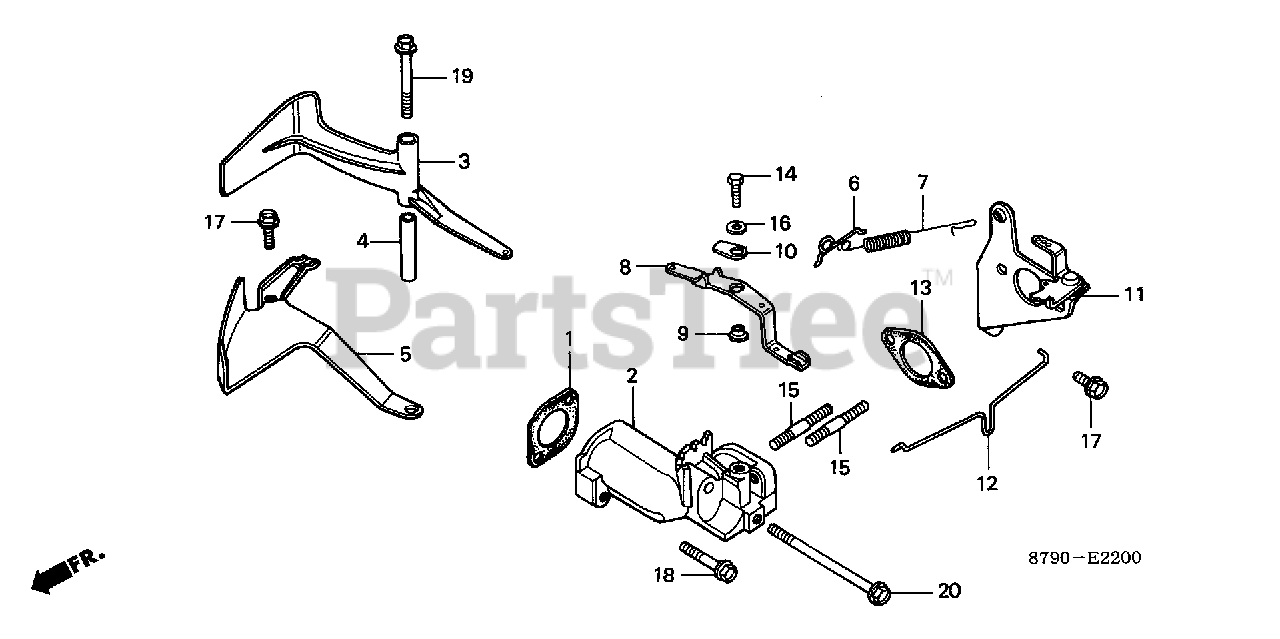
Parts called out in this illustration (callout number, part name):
1	GASKET, ELBOW (NOT AVAILABLE)
2	ELBOW, CARBURETOR (NOT AVAILABLE)
3	FLUTTER, GOVERNOR
4	COLLAR, FLUTTER
5	GUIDE, WIND
6	ROD, GOVERNOR (NOT AVAILABLE)
7	SPRING, GOVERNOR (NOT AVAILABLE)
8	LEVER, CONTROL
9	COLLAR, LEVER SETTING (NOT AVAILABLE)
10	SPRING, LEVER SETTING (NOT AVAILABLE)
11	LEVER, CHOKE (NOT AVAILABLE)
12	ROD, CHOKE (NOT AVAILABLE)
13	GASKET, AIR CLEANER ELBOW (NOT AVAILABLE)
14	BOLT, HEX. (5X14)
15	BOLT, STUD (6X37)
15	BOLT, STUD (6X25)
16	WASHER, PLAIN (5MM)
17	BOLT, FLANGE (6X12)
18	BOLT, FLANGE (6X25)
19	BOLT, FLANGE (6X45)
20	BOLT, FLANGE (6X70)
